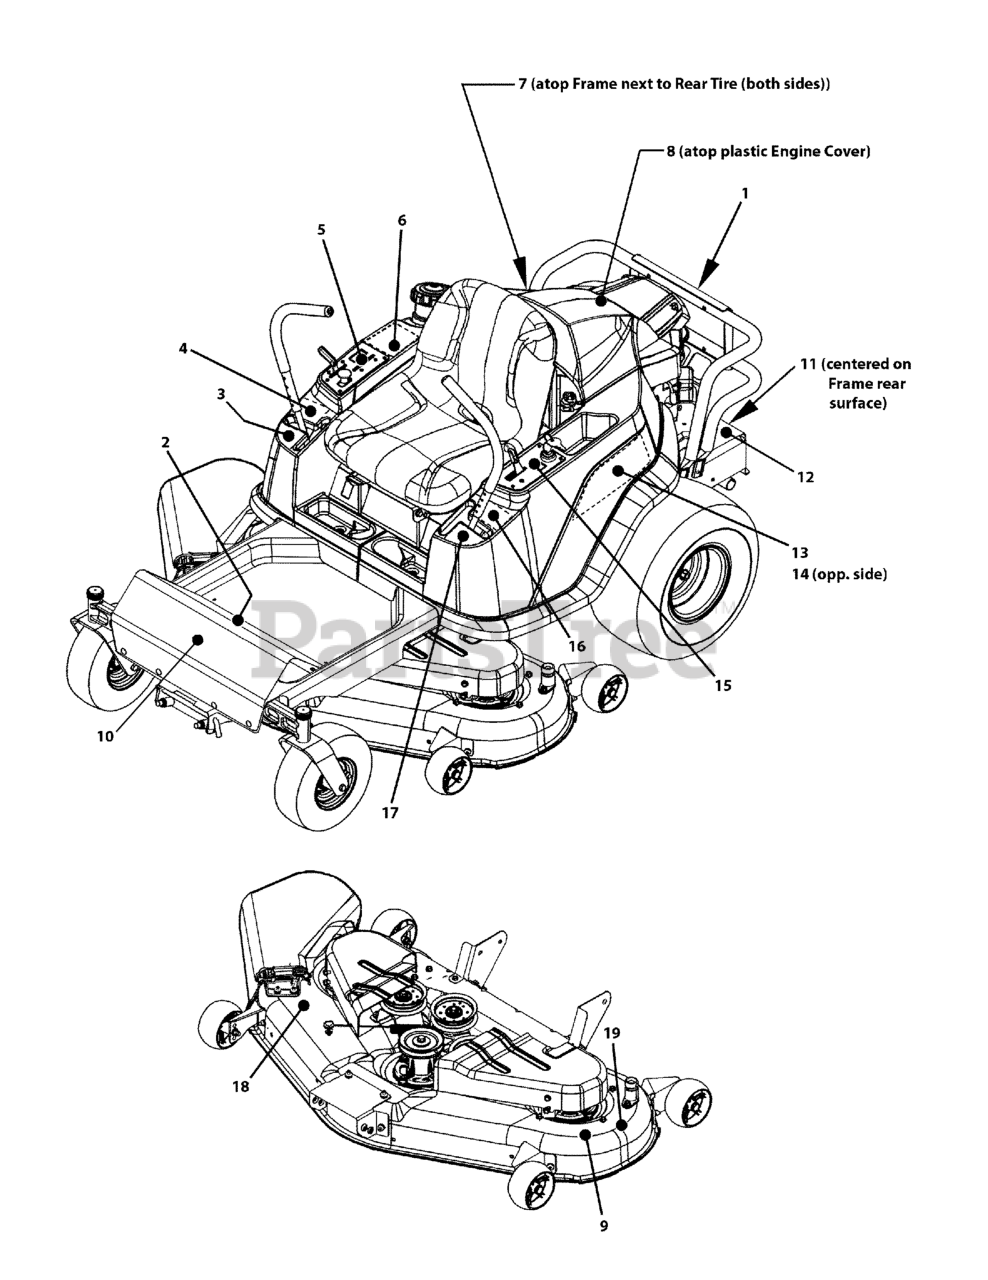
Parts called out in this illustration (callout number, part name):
1	DECAL, Rear, Craftsman ZTS
2	DECAL, DANGER, French, 285Z
3	DECAL, Handle, Ground Speed, RH, 285Z
4	DECAL, WARNING, English, RH 285Z
5	DECAL, Control Panel, RH 285Z
6	DECAL, DANGER, English, 285Z
7	DECAL, Release, Transaxle, 285Z
8	DECAL, Caution, Screen Rotating
9	DECAL, 52" Deck
10	DECAL, Model, Craftsman ZTS
11	DECAL, Weight Limitation
12	DECAL, Warning Burn Hazard
13	DECAL, LH Fender, Craftsman ZTS
14	DECAL, RH Fender, Craftsman ZTS
15	DECAL, Control Panel, LH 285Z
16	DECAL, WARNING, French, LH 285Z
17	DECAL, Handle, Ground Speed, LH, 285Z
18	DECAL, DANGER, Do Not Operate without Deflector (English/French)
19	DECAL, DANGER, Do Not Put Hands/Feet in Mower (English/French)
